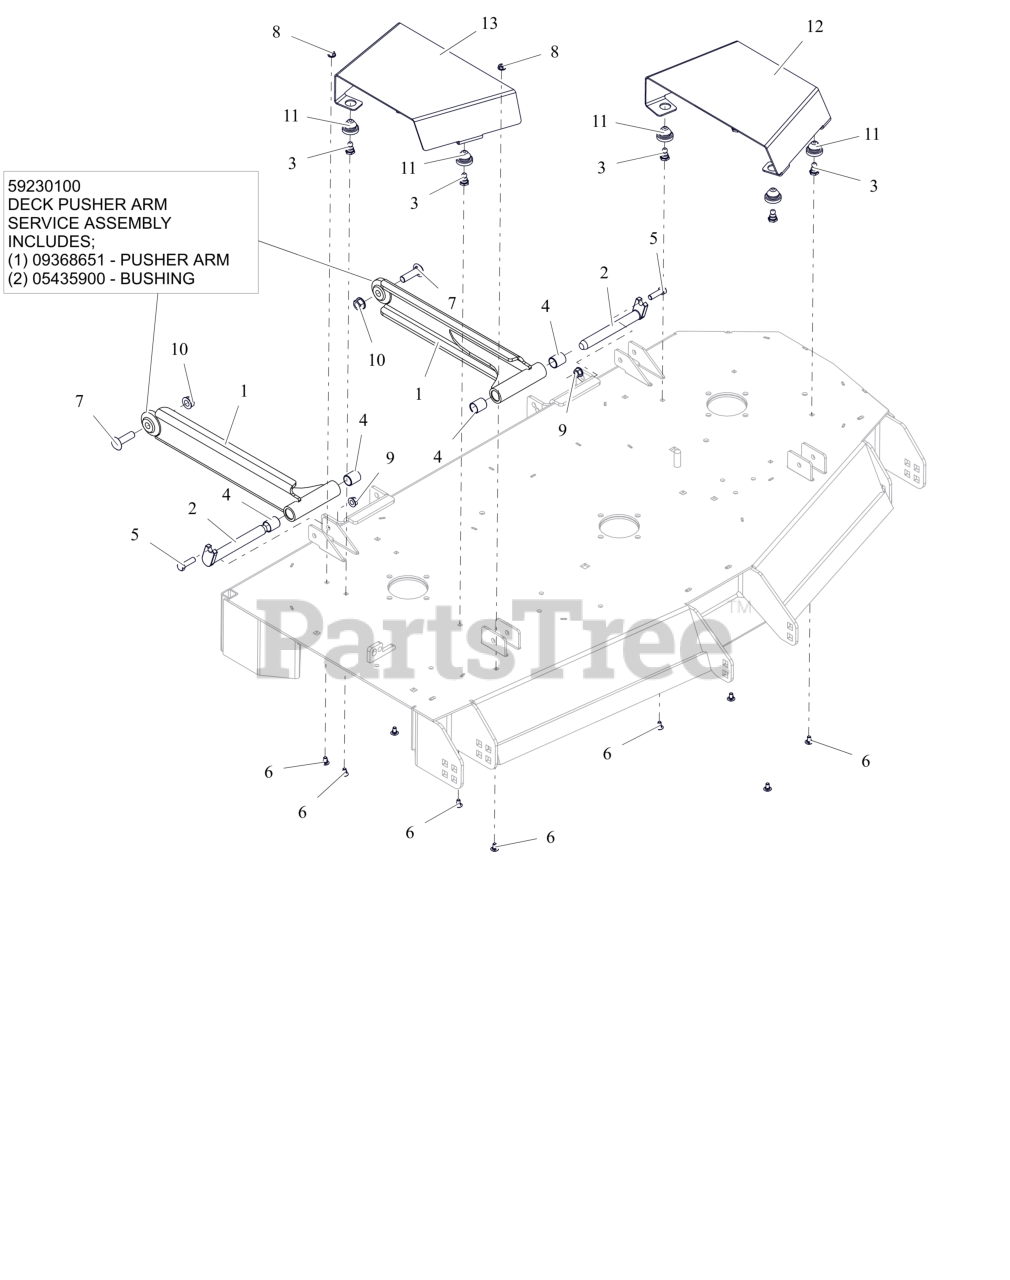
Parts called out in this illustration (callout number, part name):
1	WLDMT, DECK STABILIZER ARM (BLACK)
1	DECK PUSHER ARM SERVICE ASSEMBLY
2	PIN, MOWER MTG
3	STUD, BALL FEMALE .250-20 THREAD
4	BRG, .750 X .875 X 1.000
5	BLT, HEX .38-16X1.25 G5 ZCC
6	BLT, RHSSN.25-20X.500 G5 ZCC
7	BTL,RHSSN .500-13 X 1.75 G5 ZCC
8	NUT-LK-CTR-FLG .25-20 ZC120
9	NUT-LK-CTR-FLG .375-16 GF ZCC
10	NUT-LK-CTR-FLG .500-13 GG ZCC
11	COUPLING, RUBBER PUSH-IN
12	GUARD, LH DECK BELT (RED)
13	GUARD, RH DECK BELT (RED)
